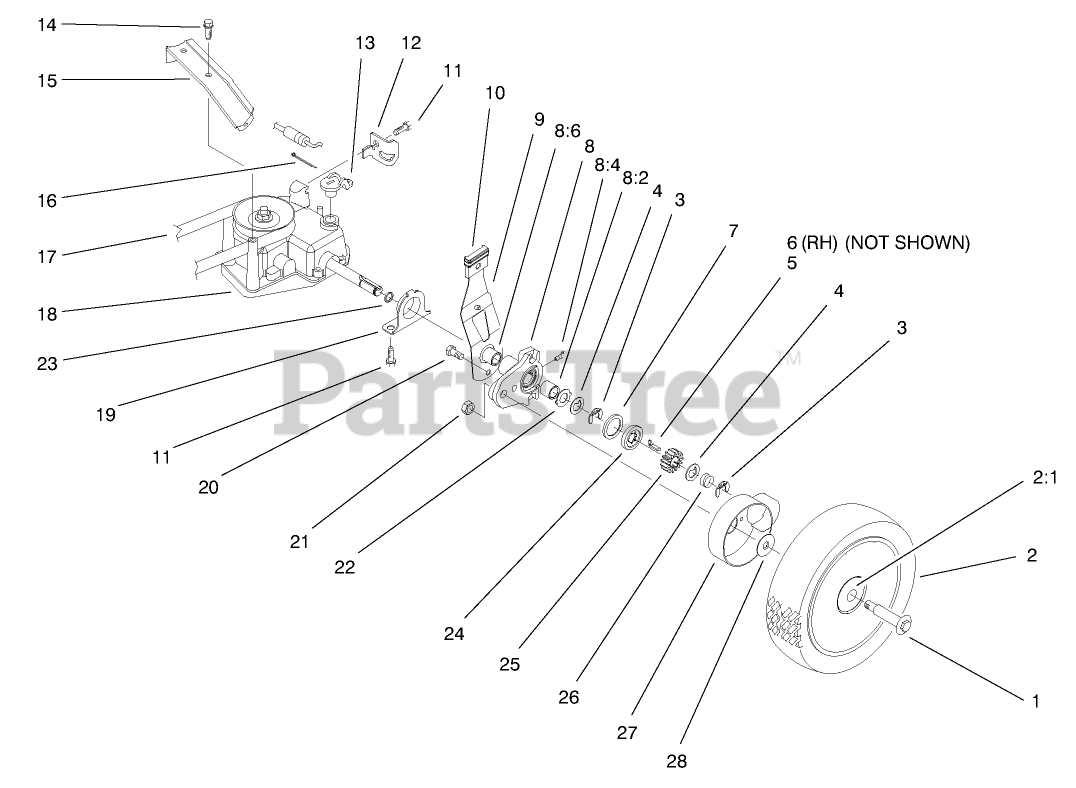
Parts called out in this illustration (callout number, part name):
1	WHEEL BOLT
2	WHL & TIRE ASSEMBLY
2:1	BUSHING
3	RING-RETAINING,CLIP
4	WASHER-THRUST, KEYED
5	KEY-ROCKING, LH
6	KEY-ROCKING, RH
7	RING-FRICTION
8	PIVOT ARM ASM
8:4	FITTING-GREASE
8:6	BUSHING
9	SPRING ARM ASM
10	KNOB-ARM
11	SCREW-HWHTF
12	RETAINER-CABLE
13	LEVER-SHIFT
14	SCREW-HWHTF
16	PIN-COTTER
17	V-BELT
18	GEARCASE ASM
19	CAP-END
20	SCREW-HSH, THREAD FORMING
21	NUT-LOCK
22	WASHER-ARM, PIVOT
23	O-RING
24	WASHER-CLUTCH
25	GEAR-PINION
26	SPRING-COMPRESSION
27	COVER-WHEEL
28	SPACER-COVER, WHEEL
